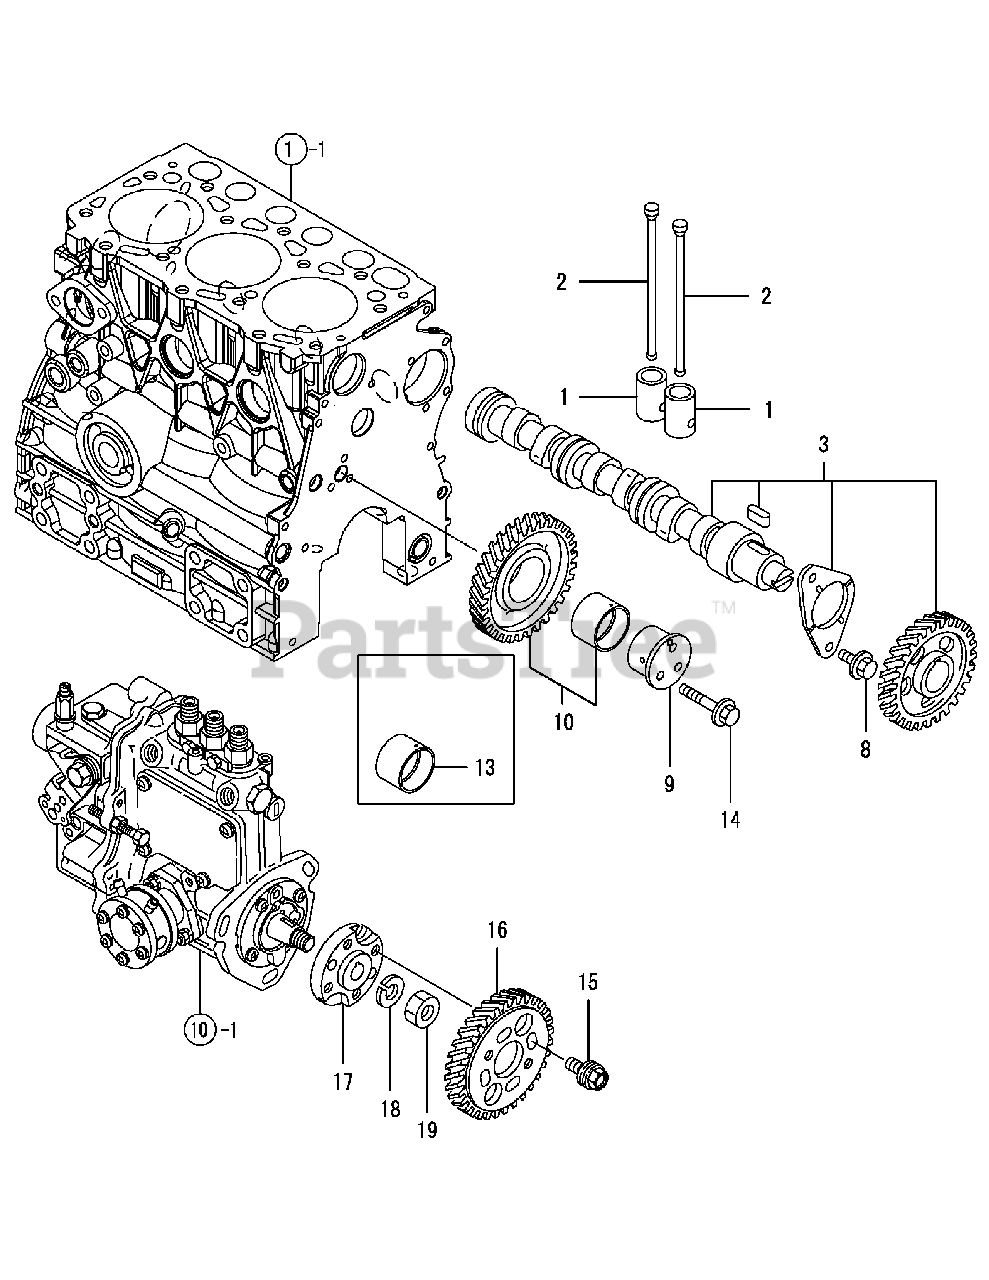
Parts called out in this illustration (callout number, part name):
3	Camshaft Assembly
8	Bolt, M 6 x 12 Plated
9	Shaft, Idle Gear
10	Gear Assembly, Idle
13	Bush, Idle Gear
14	Bolt, M 6 x 35 Plated
18	Spring Washer 12
